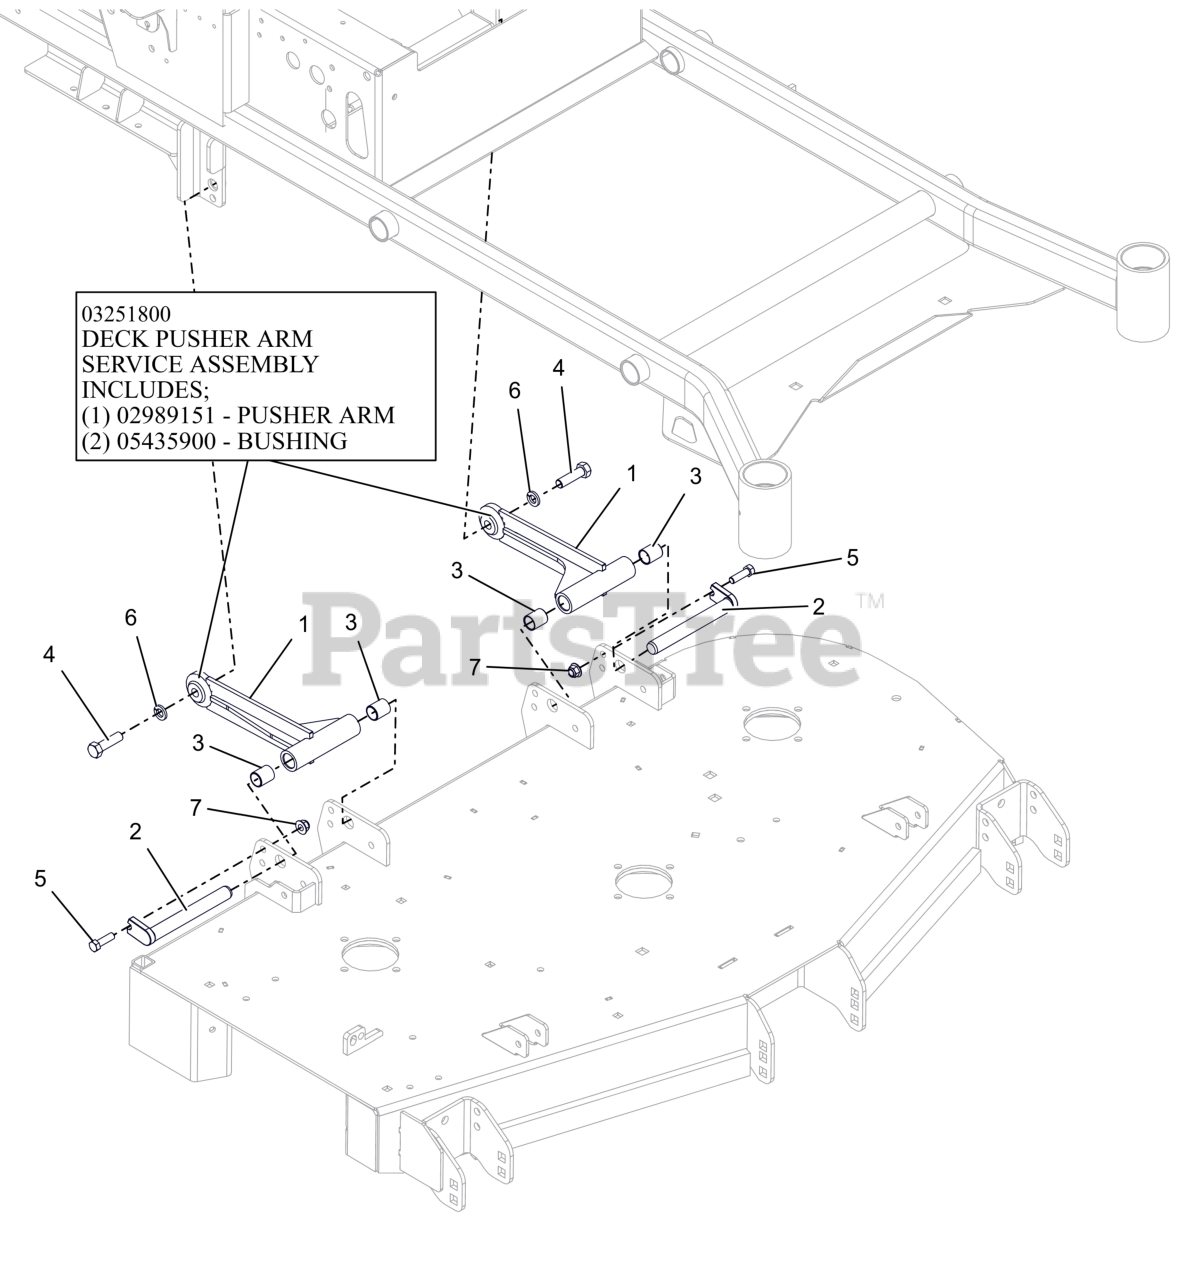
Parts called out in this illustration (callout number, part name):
1	DECK PUSHER ARM WMT - BLACK
1	DECK PUSHER ARM ASSEMBLY
1	BRG, .750 X .875 X 1.000
2	PIN, MOWER MTG
3	BRG, .750 X .875 X 1.000
4	BLT, HEX 0.5-13X1.75 GR5 ZCC EP80
5	BLT, HEX .38-16X1.25 G5 ZCC
6	WSHR,LK-REG .500X.125 ZCC
7	NUT,NYL-FLG .38-16 GF ZCC
